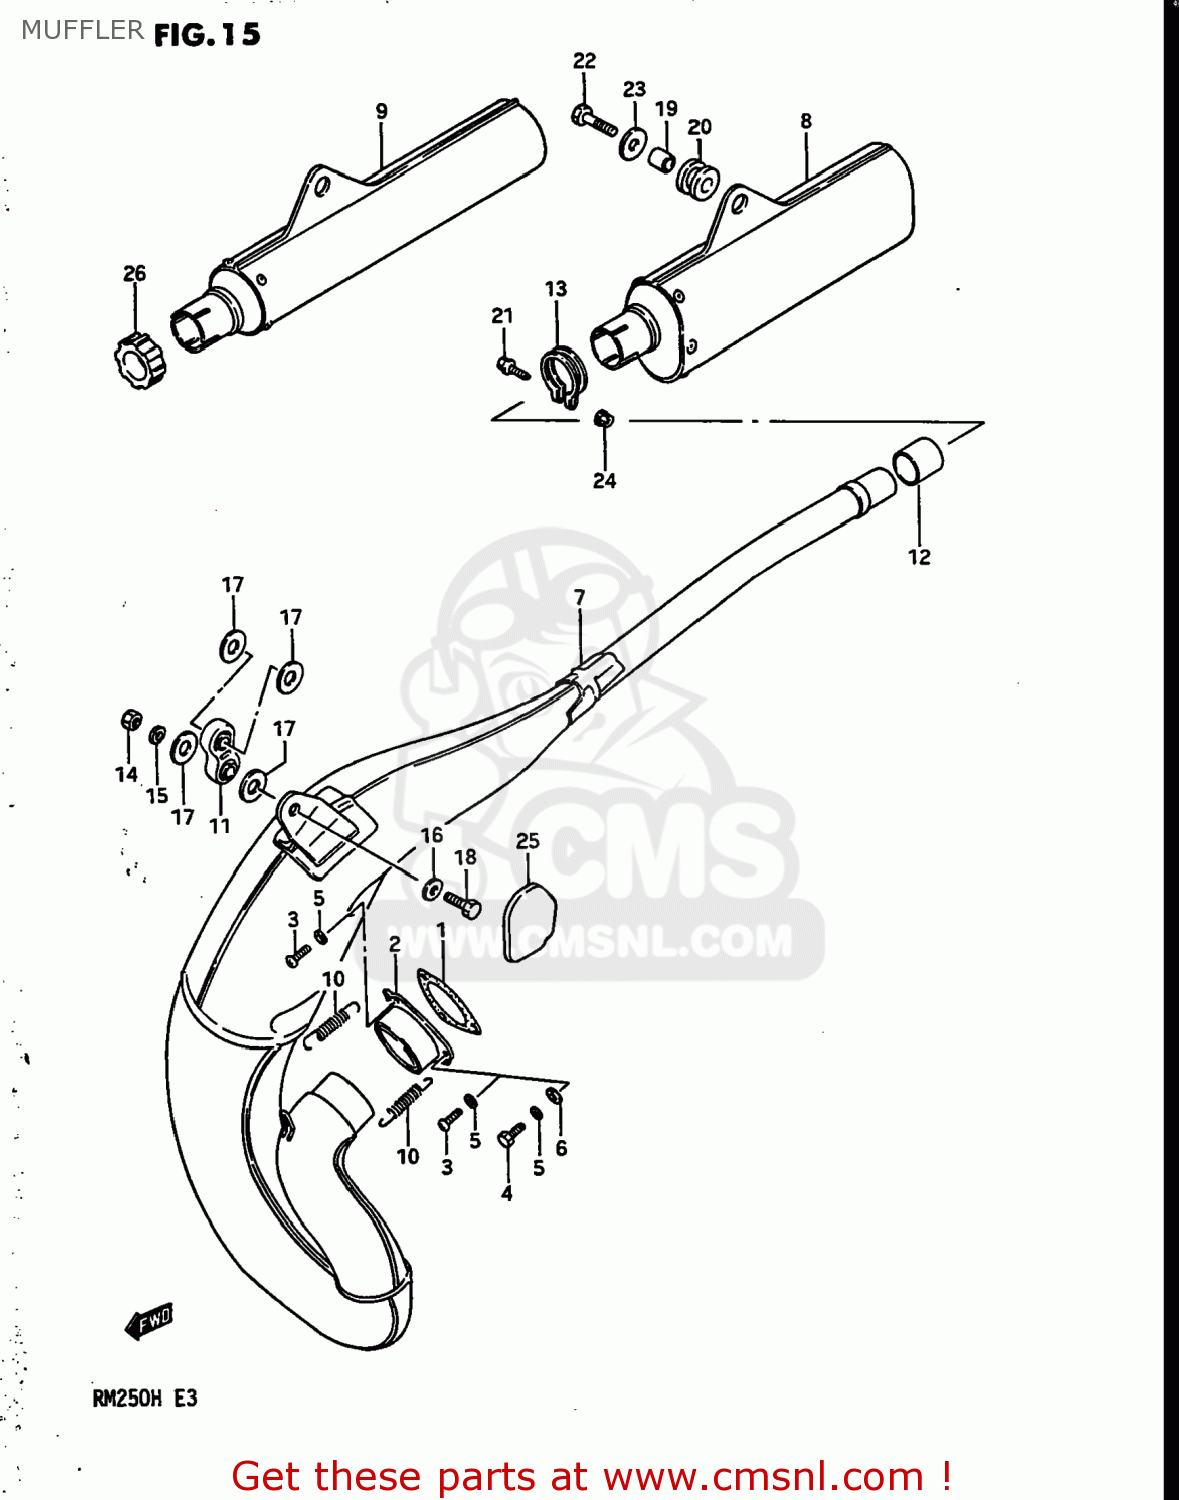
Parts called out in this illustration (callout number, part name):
1	GASKET,EXHAUST PIPE (MCA)
2	FLANGE,EXHAUST PIPE
3	SCREW
4	BOLT(6X20)
5	WASHER,LOCK
6	WASHER(6X10X2)
7	BODY,MUFFLER
8	BODY,MUFFLER
9	BODY,MUFFLER,SECOND
10	SPRING
11	DAMPER,MUFFLER
12	CONNECTOR,MUFFLER
13	CLAMP,MUFFLER 2ND
14	NUT 8MM
15	LOCK WASHER
16	WASHER
17	WASHER(13X28X1.6)
18	BOLT(8X32)
19	SPACER(8.4X12X13)
20	CUSHION
21	BOLT
22	BOLT
23	WASHER (8.5X29X1.6)
24	NUT 6MM
25	CUSHION,SPACER
26	CUSHION
